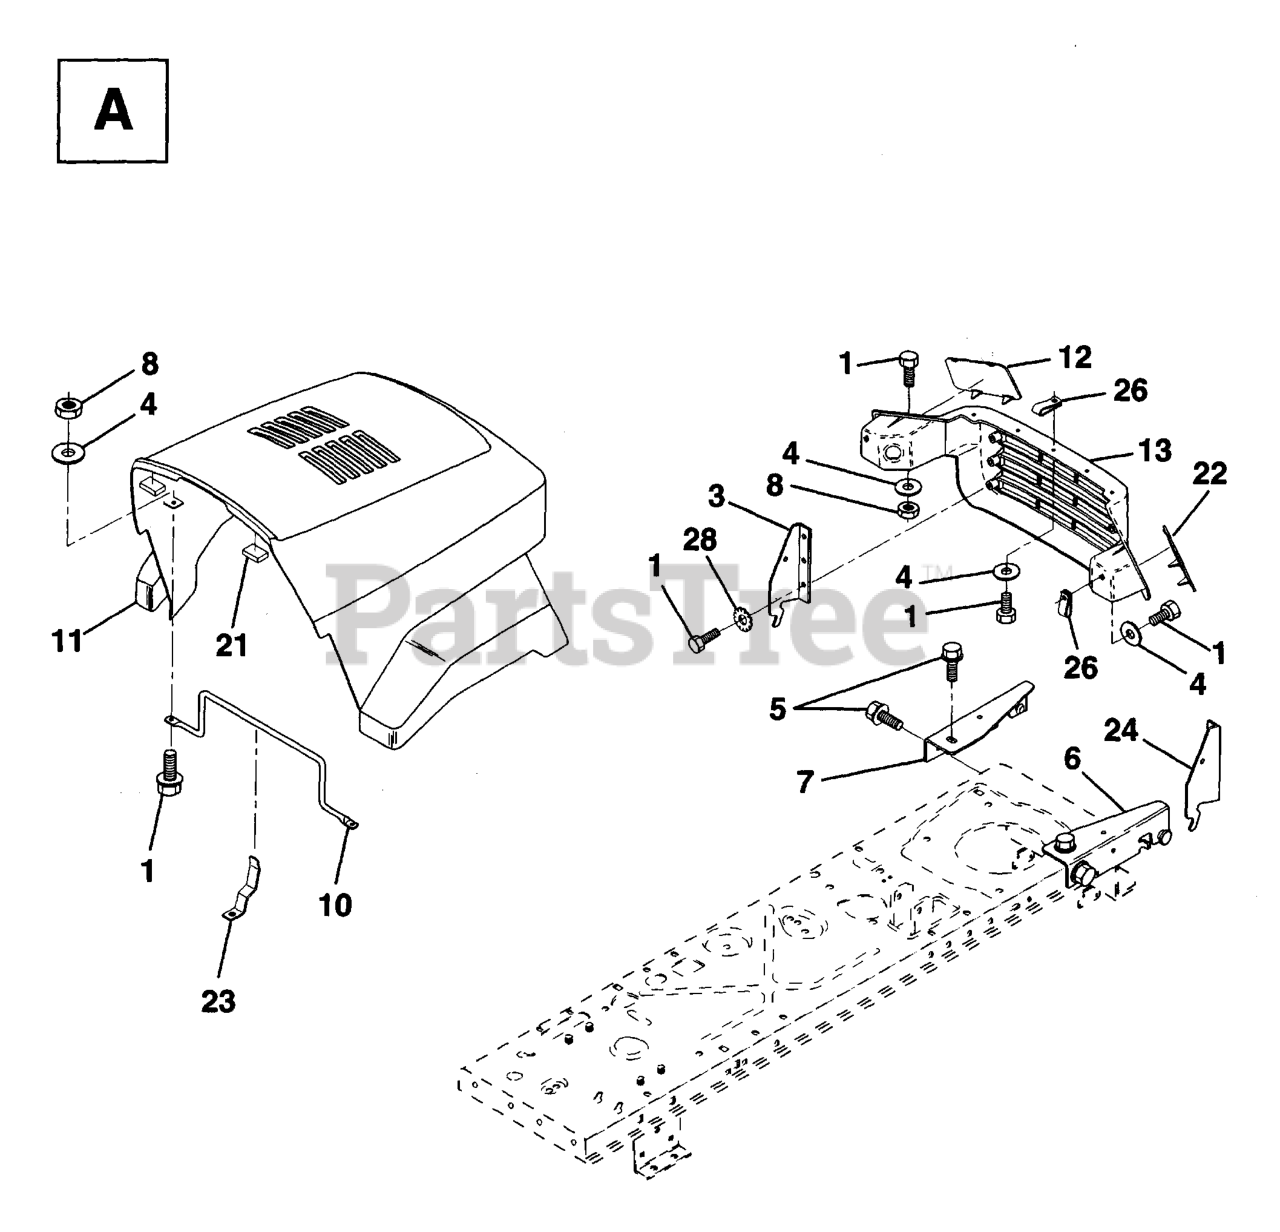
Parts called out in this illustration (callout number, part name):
1	BOLT
3	BRACKET HOOD
5	SCREW.THDROL.5/16-18X3/4.TTY
6	BRACKET ASSY HOOD
7	BRACKET ASSY
8	NUT.CROWNLOCK.1/4
10	BRACE HOOD
12	LENS.LR.LH.HUSQV.
13	GRILL
21	BUMPER HOOD T
23	HOOD LATCH
24	BRACKET PIVOT
26	CLIP TINNERMAN
28	Washer, Lock, External Tooth 1/4
